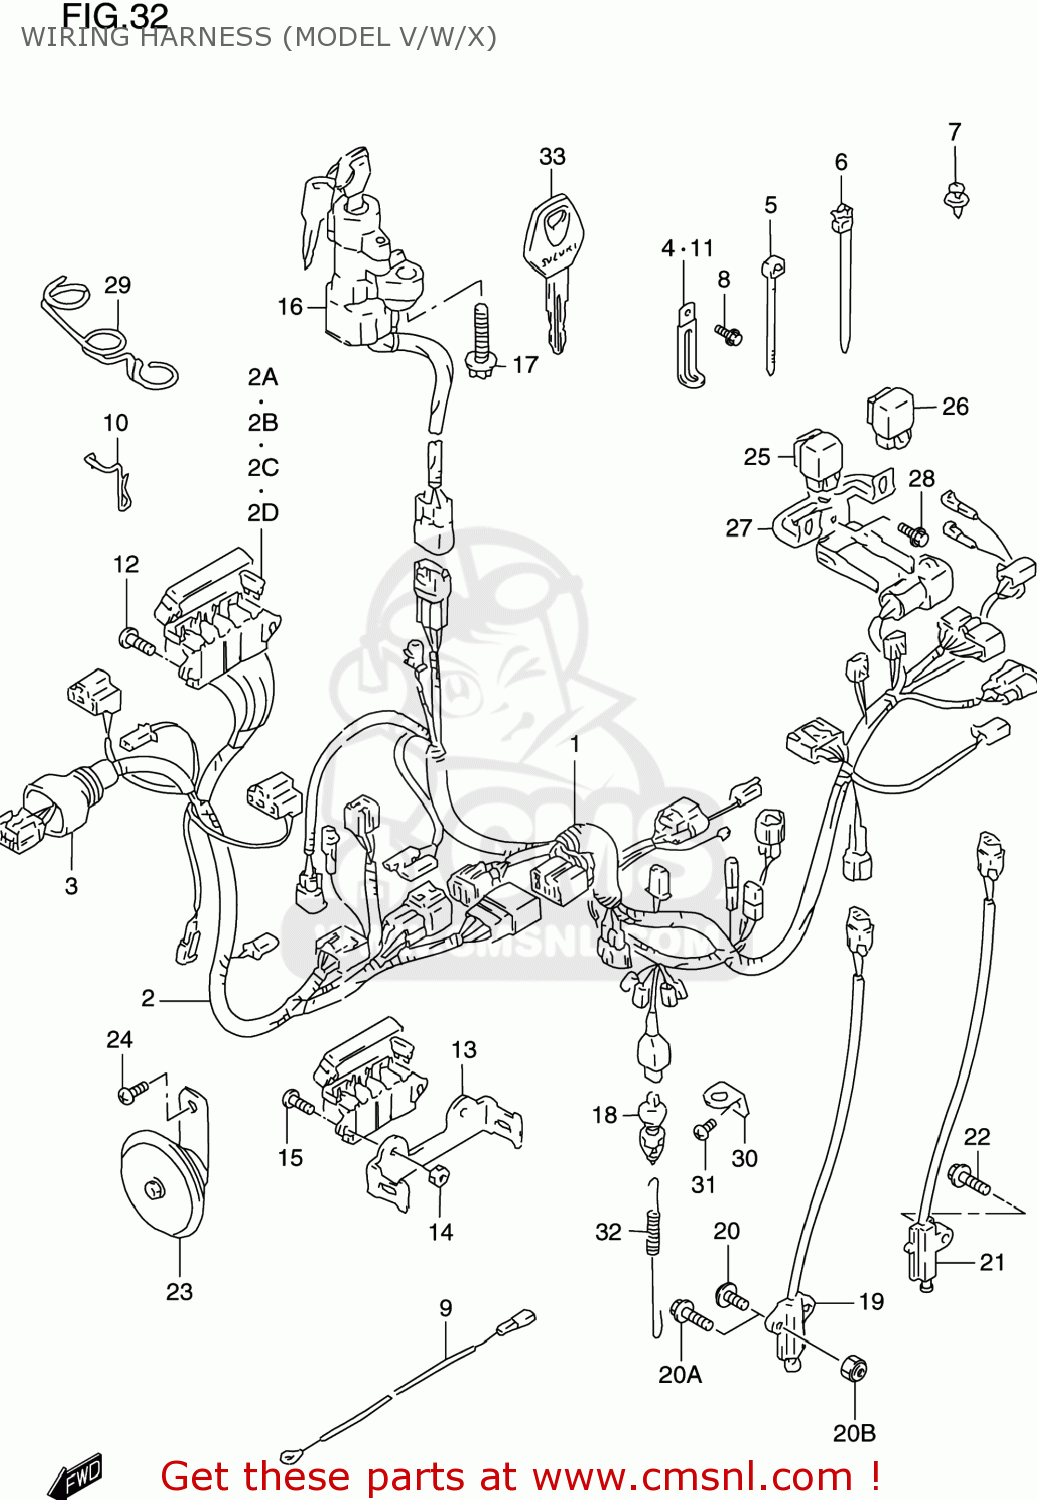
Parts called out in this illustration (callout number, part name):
1	HARNESS,WIRING NO.1
2	HARNESS,WIRING NO.2
2A	FUSE(10A)
2B	FUSE(15A)
2C	FUSE(10A)
2D	FUSE(15A)
3	COVER,SPEEDOMETER COUPLER
4	CLAMP(L:45)
5	CLAMP(L:125)
6	CLAMP
7	CLIP(BLACK)
8	BOLT
9	WIRE,OIL PRESSURE SWITCH LEAD
10	STOPPER,FUSE BOX
11	CLAMP(L:80)
12	SCREW
13	BRACKET,FUSE BOX
14	NUT,COWLING SCREEN
15	SCREW 5X12
16	LOCK ASSY,STEERING
17	BOLT(8X20)
18	SWITCH ASSY,STOP LAMP
19	SWITCH ASSY,SIDE STAND WARNING
20	BOLT 6X20
20A	BOLT
20B	NUT
21	SWITCH ASSY,SIDE STAND
22	BOLT
23	HORN ASSY
24	SCREW(8X14)
25	RELAY ASSY
26	RELAY ASSY
27	BRACKET,SIDE STAND RELAY
28	BOLT
29	GUIDE,WIRING HARNESS
30	BRACKET,STOP LAMP SWITCH
31	SCREW
32	SPRING
33	KEY,BLANK
34	LOCK SET
